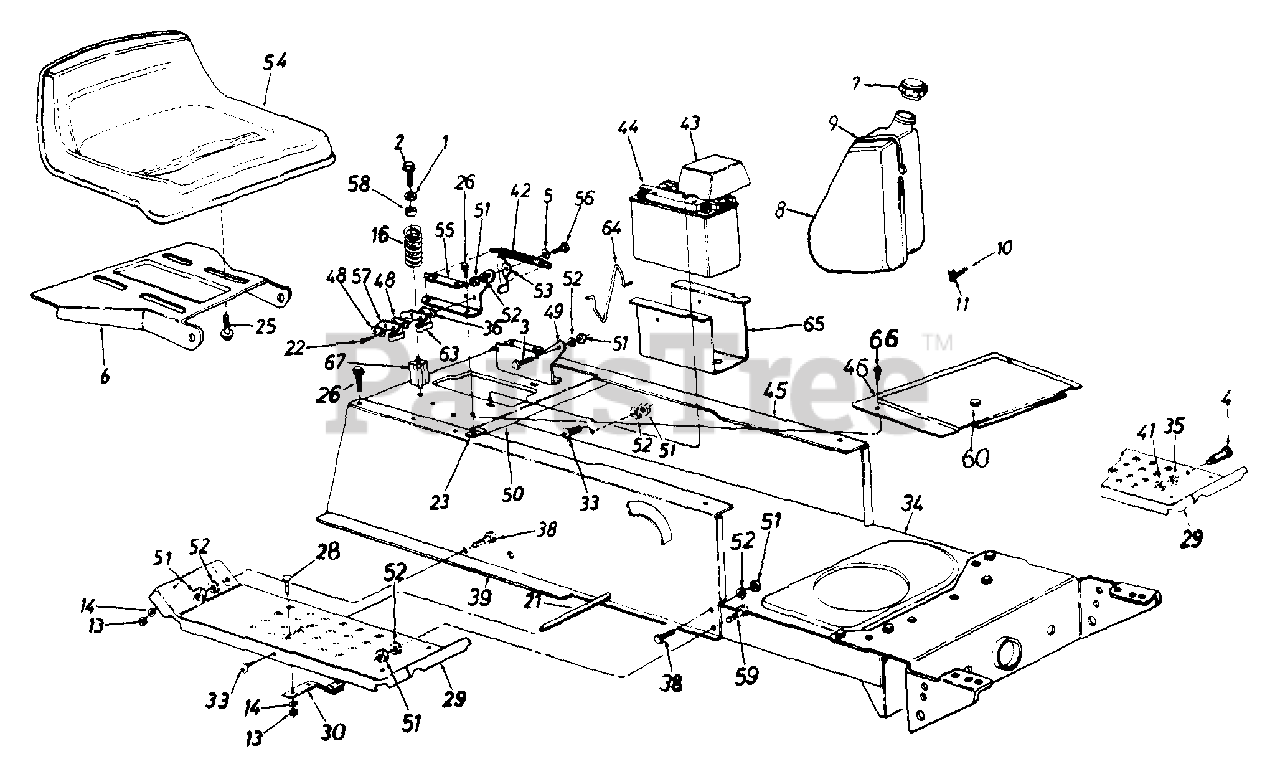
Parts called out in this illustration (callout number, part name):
1	Fl-Wash. .344" I.D. x .875"
2	Hex Wash. Hd. Tap Scr. 5/16-18 x 3.25" Lg.
3	Shld. Bolt .437" Dia. x .162"
4	Shld. Bolt .50" Dia. x .84"
5	Spr-Wash. .445" I.D. x .75
7	Fuel Cap
8	Fuel Tank
9	Tie Strap
11	Hose Clamp
13	Hex Nut 1/4-20 Thd.
14	L-Wash. 1/4" I.D.
16	Compression Spring
21	Running Board Rod
22	Hex Wash. Hd. AB-Tap Scr. #8 x .50" Lg.
23	Speed Nut #10Z
25	Hex Tap Scr. 3/8-16 x .75"
26	Hex Wash. Hd. AB-Tap Scr. 5/16 x .75" Lg.
28	Carriage Bolt 1/4-20 x .62"
29	Running Board (R.H. & L.H.)
30	Blade Brake Ass'y.
33	Pan Hd. Cutting Scr. 5/16-18 x .75" Lg.
34	Lower Frame
35	L-Wash. 3/8" I.D.
36	Insulator Boss Plate
38	Hex Bolt 5/16-18 x .75" Lg.
39	Upper Frame - R.H.
41	Hex Nut 3/8-16 Thd.
42	Extension Spring 5.31" Lg.
43	Battery Cover
44	12-V Battery
45	Upper Frame - L.H.
46	Shift Cover
48	Insulator Plate
52	L-Wash. 5/16" I.D.
53	Seat Lift Brkt.
56	Shld. Bolt .437" Dia. x .268"
57	Spring Switch
59	Hex Wash. TT-Tap Scr. 5/16-18 x 7/8" Lg.
60	Snap Bushing
63	Safety Switch (Seat)
64	Battery Tray Clip
65	Battery Tray
66	Truss Mach. B-Tap Scr. #10 x .5" Lg.
67	Spring Spacer
